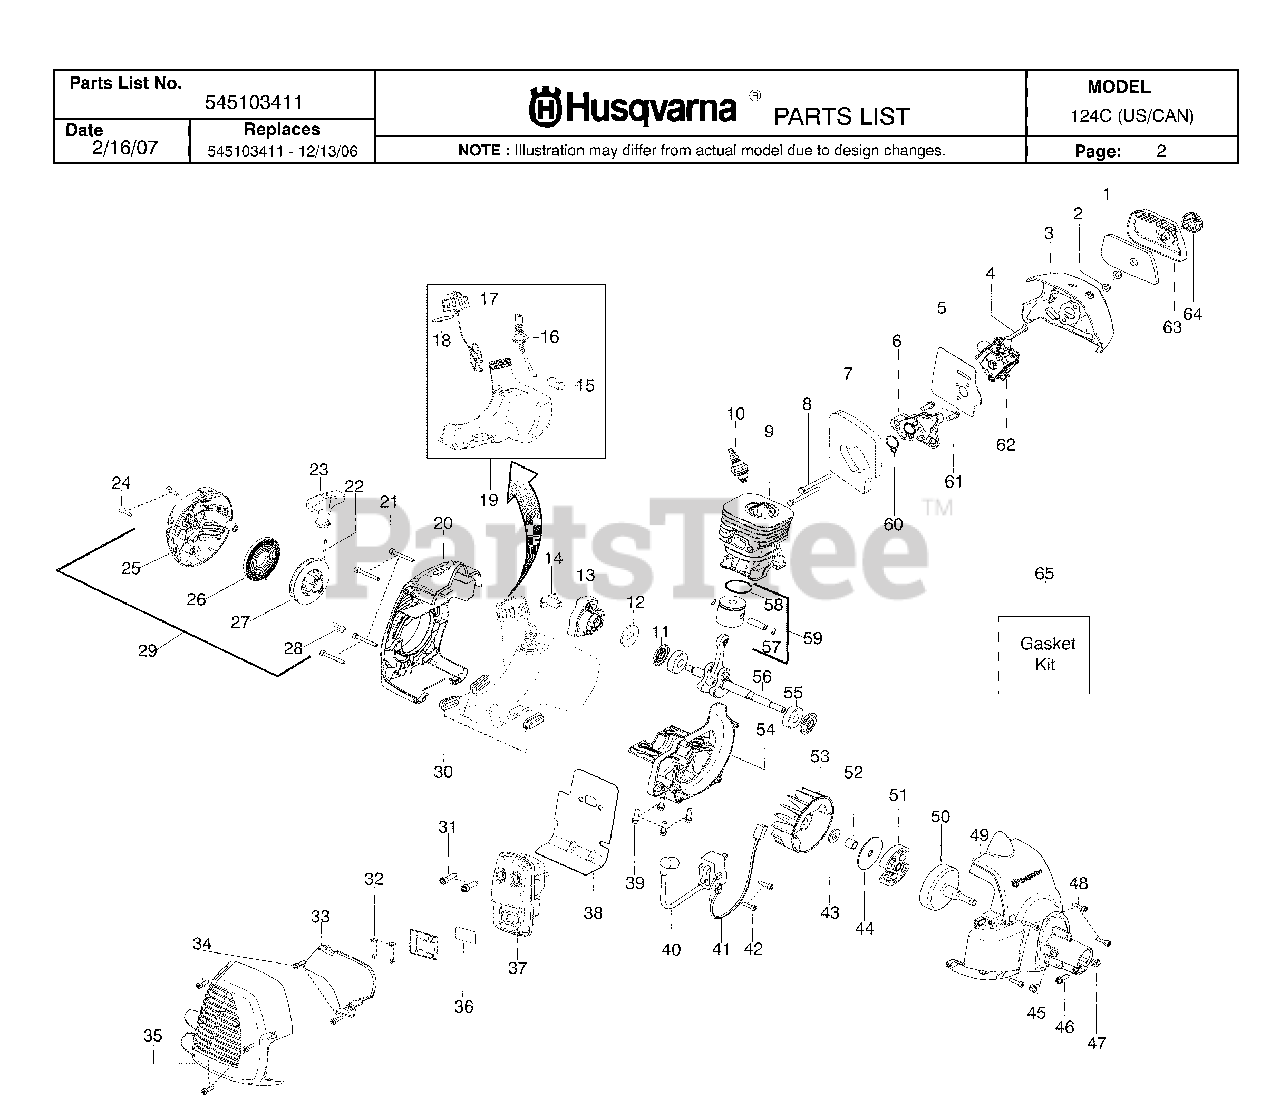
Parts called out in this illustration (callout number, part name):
2	Nut-Carb. Screw
3	Air Box
4	Lever - Choke
5	Kit-Carb. Gasket
6	Adaptor-Carb.
7	Kit-Gasket
9	Cylinder
10	Plug-Spark
11	Kit-Crankshaft seal
12	Washer - Flat
13	Assy - Starter Cup
14	Coupling - Starter
15	Assy - Fuel Filter
16	Kit - Fuel Line
17	Assy-Cap w/ret.
18	O-ring - Fuel Cap
19	Assy-Fuel Tank
20	Shroud-Rear
23	Handle-Starter
25	Starter Hsg. w/eyelet
26	Kit-Starter Spring
27	Kit-Starter Pulley
29	Assy-Starter Hsg.
30	Isolator-Tank
31	Bolt-Muffler
33	Shield-Heat
35	Guard-Muffler
36	Kit-Spark Arrestor
37	Assy-Muffler
38	Gasket-Paper Metal
40	Module
41	Assy-Leadwire
44	Washer-Clutch
49	Assy-Fan Housing
50	Assy-Clutch Drum
51	Kit-Clutch Assy.
56	Kit-Crankshaft
57	Retainer-Piston Pin
58	Ring-Piston
59	Kit-Piston
60	Kit-Gasket
62	Kit-Carb.
63	Cover-Air Box
65	Kit-Gasket
